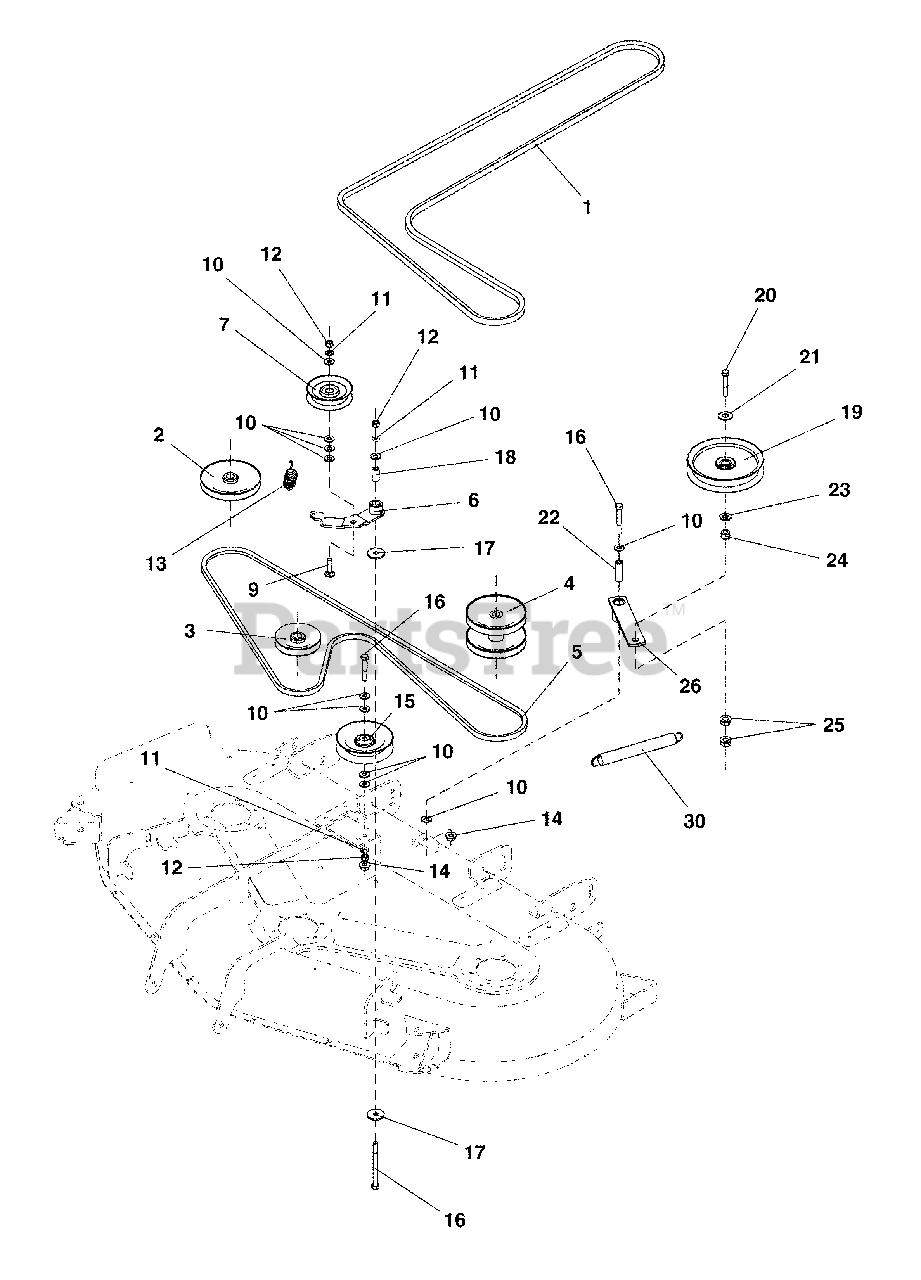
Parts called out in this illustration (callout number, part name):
2	PULLEY ASSEMBLY, RH
3	PULLEY ASSEMBLY, Center
4	PULLEY ASSEMBLY, LH
5	BELT, Deck Drive
6	IDLER ARM ASSEMBLY
7	PULLEY ASSEMBLY
9	CARRIAGE BOLT, 3/8-16 x 1-1/2
10	WASHER, 3/8
11	BEARING, Roller (2 per tire)
12	NUT, Hex, 3/8-16
13	SPRING, Deck Drive
14	NUT, Hex Flange, 3/8-16
15	PULLEY, Idler
16	CAPSCREW, Hex Hd, 3/8-16 x 2-1/4
17	WASHER
19	*PULLEY, FLAT IDLER, 6-3/4"
20	CAPSCREW, Hex Hd, 1/2-13 x 3
21	WASHER, 1/2
23	WASHER, 1/2
25	NUT, Hex Flange Lock, 1/2-13
26	IDLER ARM ASSEMBLY, Complete (Includes Ref 27-29)
27	LEVER, Idler
29	GREASE FITTING
